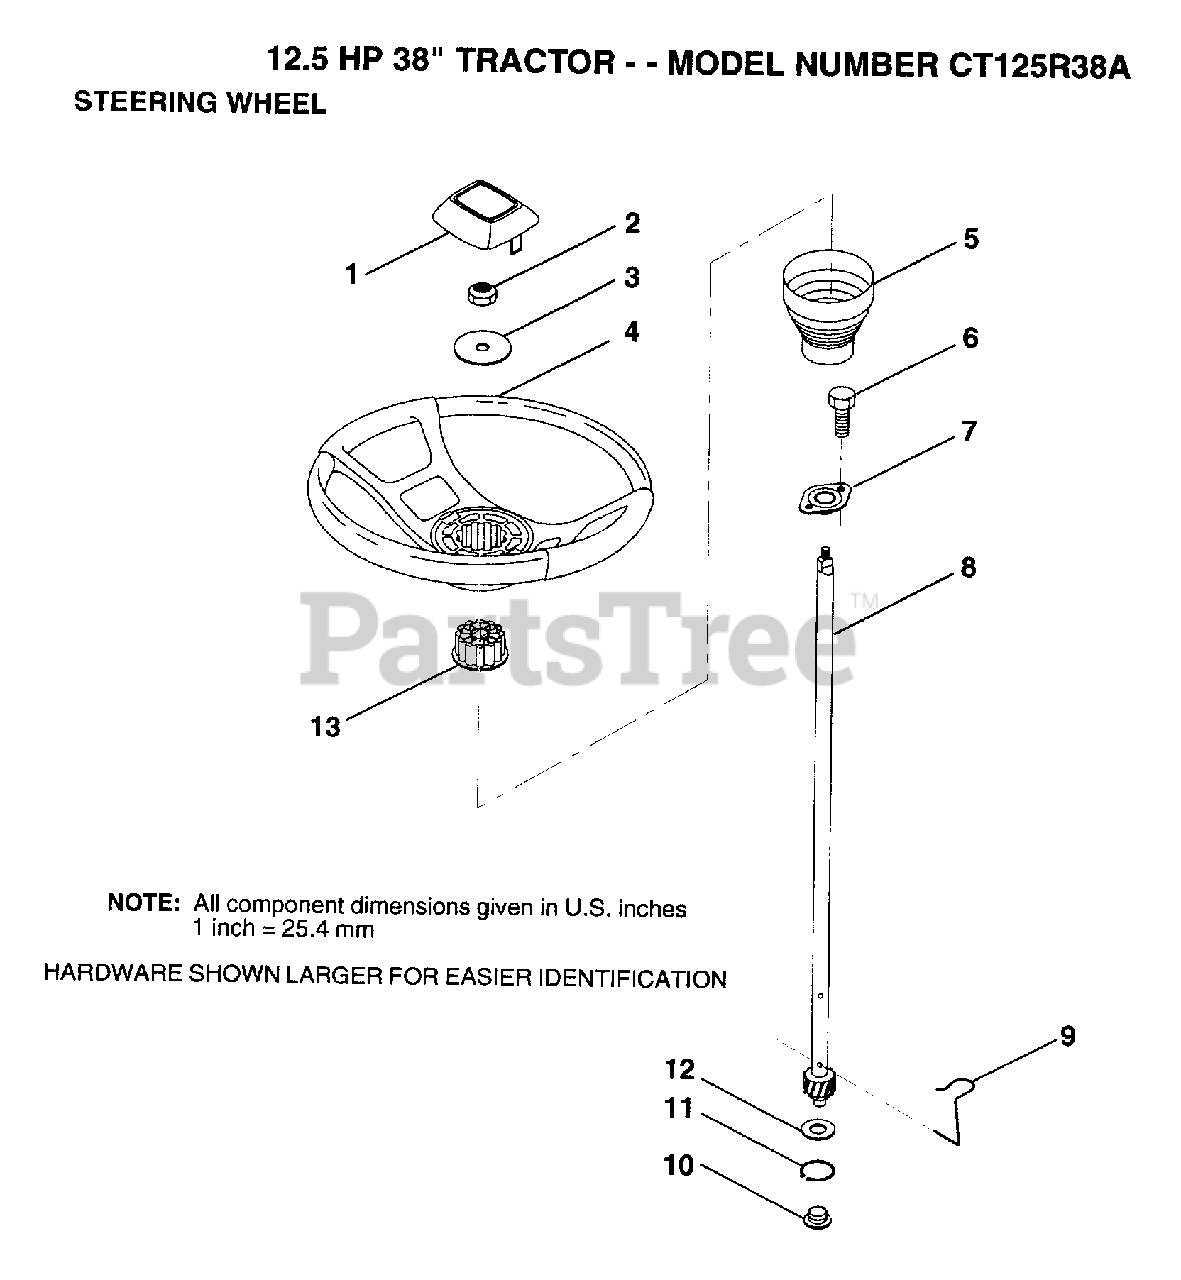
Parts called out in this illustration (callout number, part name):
1	ST WHL INSERT CAP
2	GRIPCO NUT
3	WASHER T
5	SLEEVE STEERING
7	CABLE GUIDE TI
9	STEERING CLIP
10	BUSHING STEER LWR
11	RING
12	WASHER LT
13	ADAPTER-WHEEL LT
